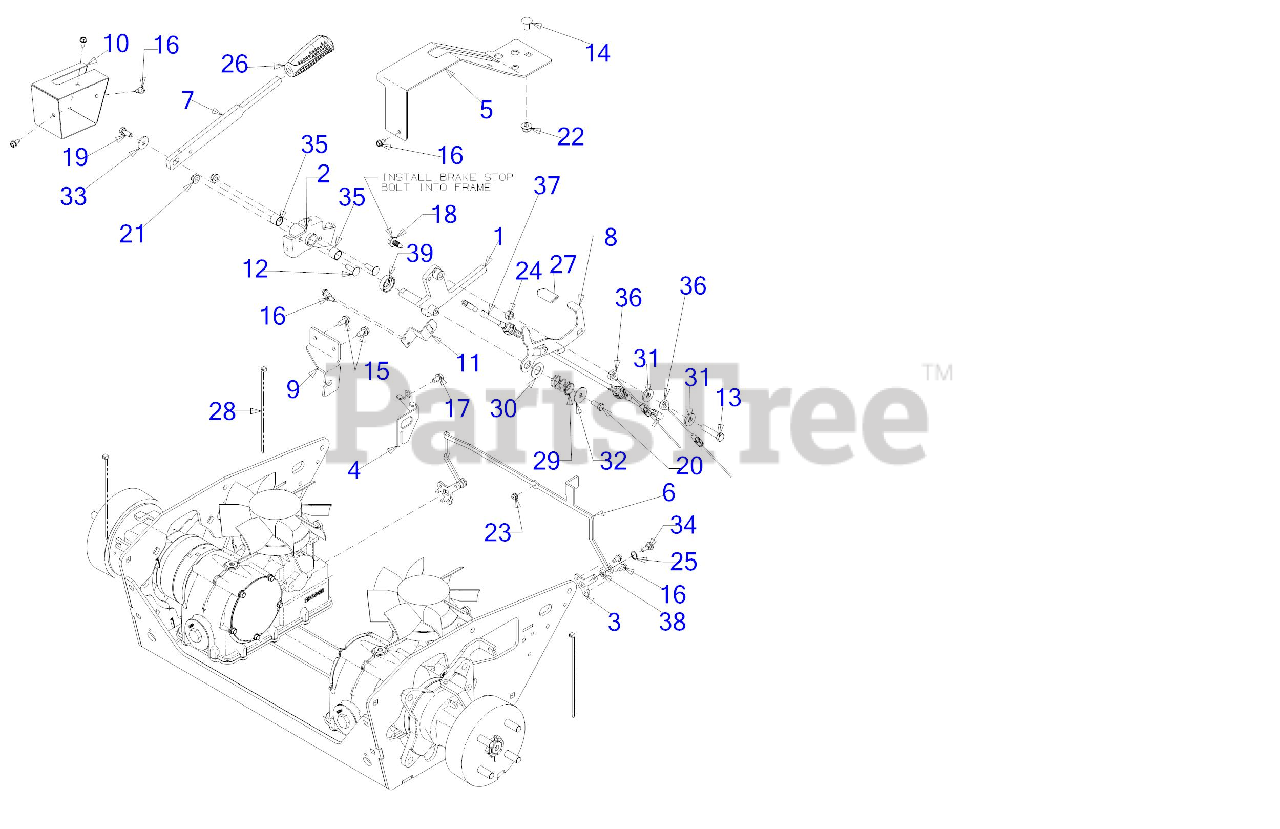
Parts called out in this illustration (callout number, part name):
1	PIVOT BRAKE SHAFT ASSEMBLY
3	TRANSMISSION BYPASS LEVER
6	DUMP VALVE ACCTUATOR BRACKET
8	DUMP VALVE RELEASE LEVER
12	CARRIAGE BOLT 5/16-18 x 1.00
13	HEX SCREW 3/8-16 x 1.75 GR5
14	CARRIAGE BOLT 3/8-16 x .750 GR5
15	SCREW 5/16-18 x .750
16	SCREW 1/4-20 X.500
17	SCREW 5/16-18 x .500
18	HEX SCREW WASH TT 3/8-16 x .875
19	SCREW 5/16-18 x .750
20	SCREW 5/16-18 x .75 GR5
21	FLANGE LOCK NUT 5/16-18
24	HEX NUT
25	SNAP RING
27	SEAT ADJUSTER GRIP
28	7" CABLE TIE
29	COMPRESSION SPRING .844X.970X1.50
30	FLAT WASHER .640ID X1.24OD x .06
31	FLAT WASHER .385 x 1.00 x .135
32	FLAT WASHER .322 ID x 1.25 x .060
33	FLAT WASHER 1.0 OD:.331 ID
34	SHOULDER SCREW .375X.280:1/4-14
35	SLEEVE BEARING
36	BRAKE CABLE
37	NEUTRAL CONTROL CABLE
